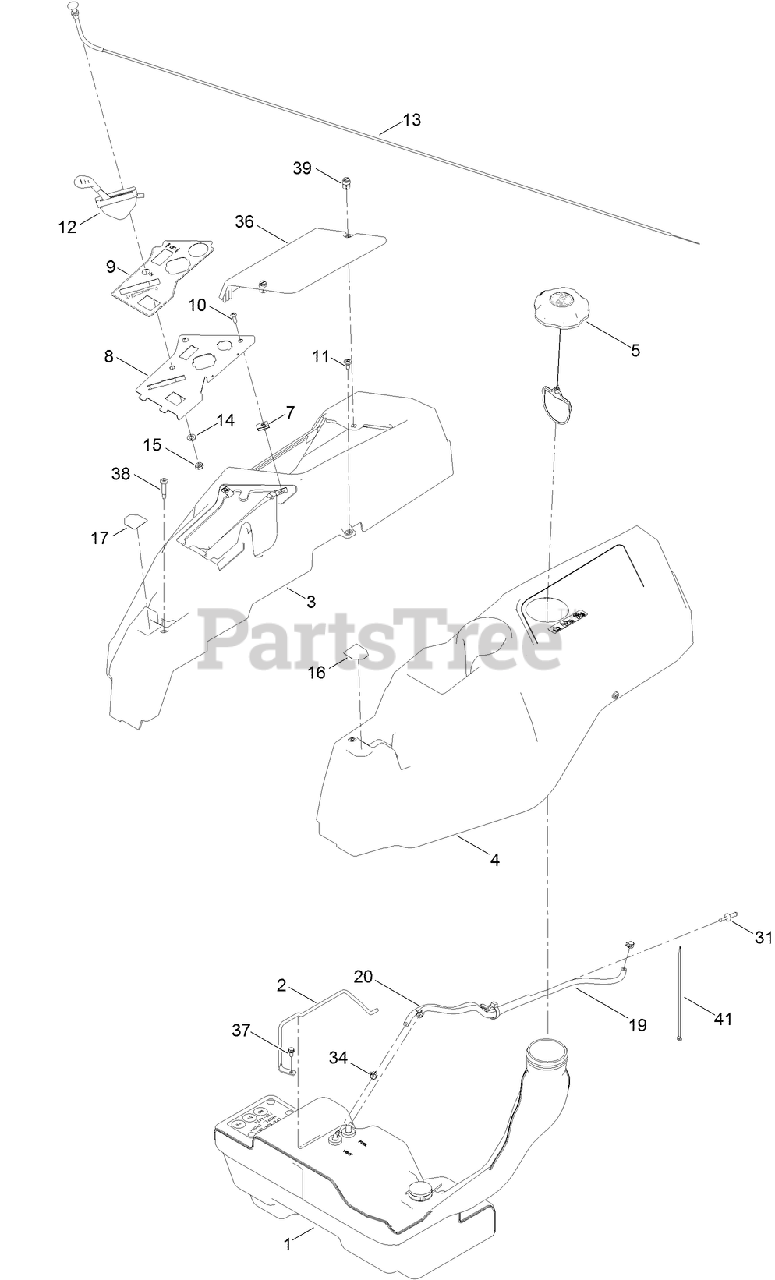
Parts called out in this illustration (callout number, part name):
1	FUEL TANK ASM
2	ROD-HOLD DOWN
3	POD-RH
4	POD-LH
5	CAP-FUEL, RATCHETING
8	PANEL-CONTROL
9	DECAL-CONTROL W/CHOKE
10	SCREW-PRH
11	SCREW-SHOULDER
12	CABLE-THROTTLE
13	CABLE-CHOKE
14	WASHER-LOCK
15	NUT-HJ
16	DECAL-LEVER, CONTROL (LH)
17	DECAL-LEVER, CONTROL (RH)
19	HOSE-FUEL
20	HOSE-FUEL
31	ADAPTOR-ORIFICE
34	CLAMP-HOSE
36	COVER-BATTERY
37	SCREW-HWH
38	SCREW-SHOULDER
39	FASTENER
41	TIE-CABLE
